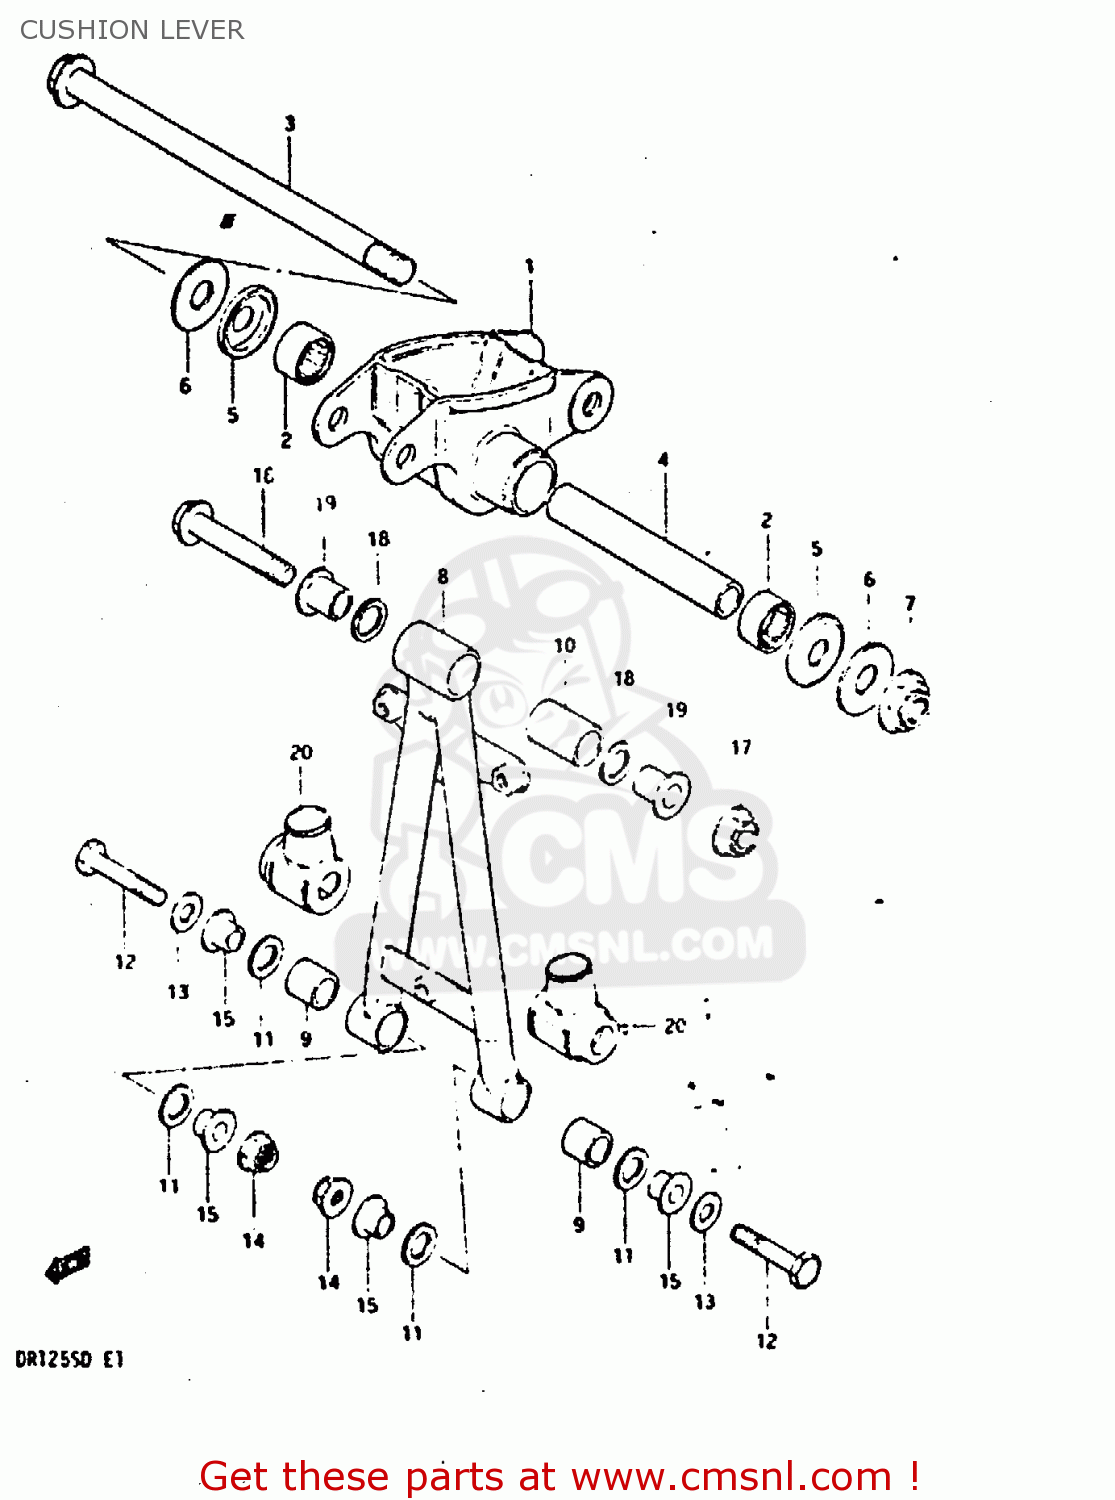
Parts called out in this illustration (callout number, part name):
1	LEVER SET,REAR CUSHION
2	BEARING(17X25X20)
3	SHAFT,REAR CUSHION LEVER
4	SPACER
5	DUST SEAL,RR CUSHION LEVER
6	WASHER
7	NUT 12MM
8	ROD SET,REAR CUSHION LEVER
9	BUSHING
10	BUSH,UPPER
11	DUST SEAL,RR CUSHION LOD LWR
12	BOLT,REAR CUSHION ROD
13	WASHER
14	NUT
15	SPACER,RR CUSHION ROD LWR
16	BOLT(10X65)
17	NUT
18	DUST SEAL,LEVER CUSHION UNIT
19	SPACER,RR CUSHION ROD UPR
20	BOOT,REAR CUSHION ROD,LOWER
